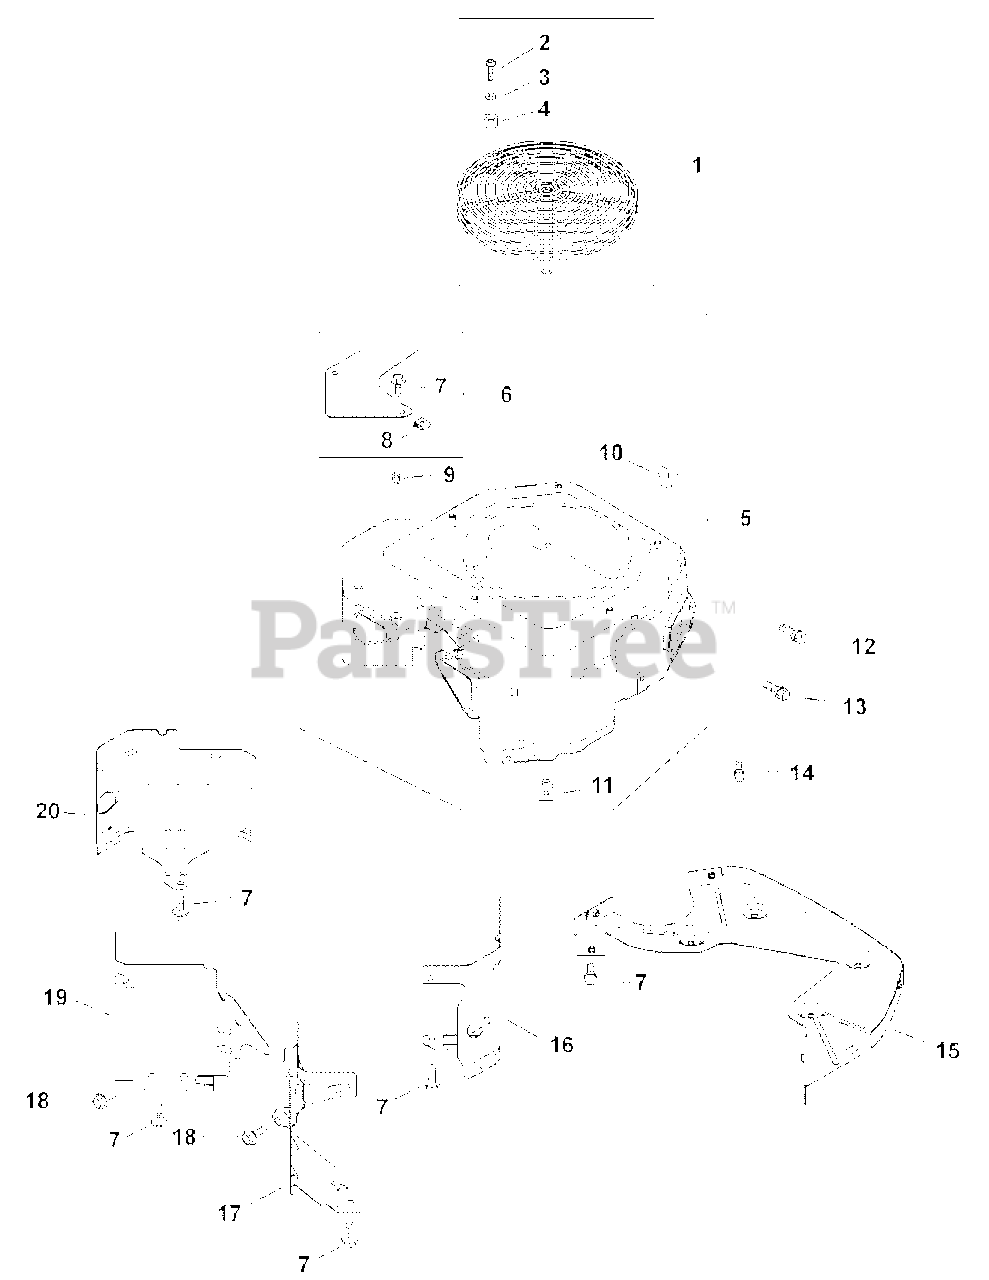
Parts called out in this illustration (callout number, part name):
1	Kit, Guard
2	Screw, Lbd Skt Pan M5x0.8x15
3	Washer, Flat 7/32
4	Spacer
5	Housing, Blower
6	Kit, Access Panel
7	Screw, Flg Thd Frm M6x1.0x16
8	Clip, Mounting
9	Screw, Skt Set #10-24x1/4"
10	Nut, Plastic
12	Screw, Flg Thd Frm M5x0.8x16
13	Screw, Flg Thd Frm M5x0.8x20
14	Screw, Flg Thd Frm M5x0.8x16
15	Plate Backing
16	Baffle, Cyl Barrel #2 Side
17	Baffle, Valley #2 Side
18	Screw, Flg Thd Frm M5x0.8x10
19	Baffle, Valley #1 Side
20	Baffle, Cyl Barrel #1 Side
21	Screw, Phl Hd #11-16x7/8"
22	Strap, Breather
23	Bracket, Breather Seperator
